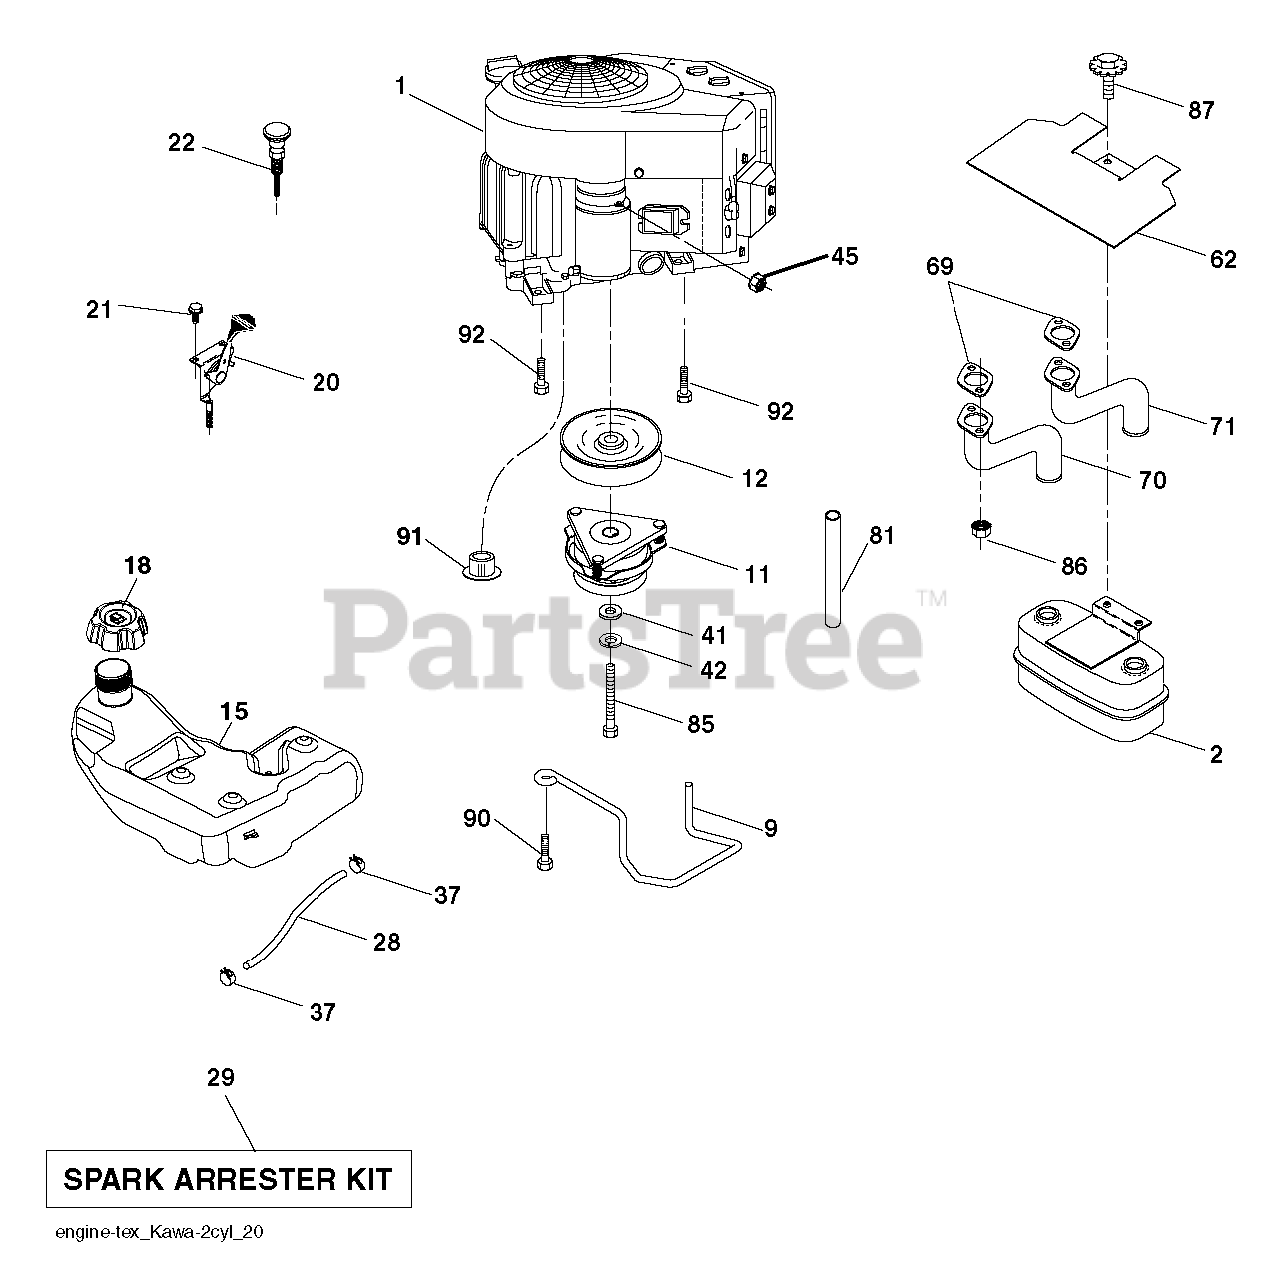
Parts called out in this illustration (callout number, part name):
2	MUFFLER.TWIN.CYL.LOW.TONE
9	KEEPER.BELT.ENGINE.3.25 (3 2)
11	RB.CLUTCH.OGURA.4.4.PD
12	PULLEY.ASM.ENG.OGURA.3
15	TANK.FUEL.4GAL
18	CAP.FL.R.3'N/CARB.H.CROWN.498
20	THROTTLE CABLE
21	SCREW.#10 X 0.750.BOS
22	CONTROL, CHOKE
28	REPL BY 532 00 85-43
29	KIT.SPARK ARRESTOR 794945 B&S
37	HOSE CLAMP
42	LOCKWASHER
45	NUT
62	SHIELD.HEAT.MUFFLER
70	EXHAUST.TUBE.LH.KAWASAKI.
71	EXHAUST.TUBE.RH.KAWASAKI.
81	TUBE, DRAIN OIL ASM.
85	BOLT HEX 7/16-20X4-1/4"
86	NUT.HEX.FLANGE.TOPLOCK
87	BOLT.5/16-18UNCX1.W/SEMS.BLK
90	SCREW 3/8-16X1
91	BUSHING.1.375OD
92	SCREW 3/8-16X1
